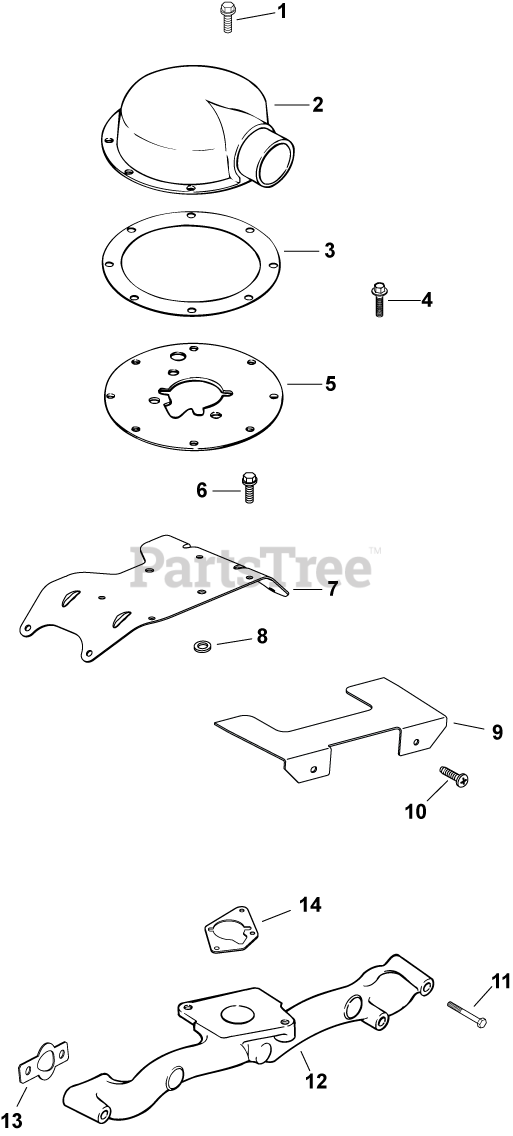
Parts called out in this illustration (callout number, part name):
1	SCREW,FLG THD FRM M6X1.0X16-(#25086397S)
2	ADAPTER, AIR INTAKE
3	GASKET, AIR CLEANER ADAPTER
4	SCREW, HVY FLG M5X.8X16
5	PLATE, ADAPTER-USE 24 029 83-S
6	SCREW, FLG M6X1.0X16
7	BRACKET, AIR CLEANER-USE 24 126 213-S
9	SHIELD, DEBRIS
10	SCREW, PHL HD 11-16X3/4"
11	SCREW, FLG M6X1.0X55
12	MANIFOLD, METAL INTAKE
13	GASKET, INTAKE MANIFOLD USE 24 041 79-S
14	GASKET, AIR CLEANER BASE
